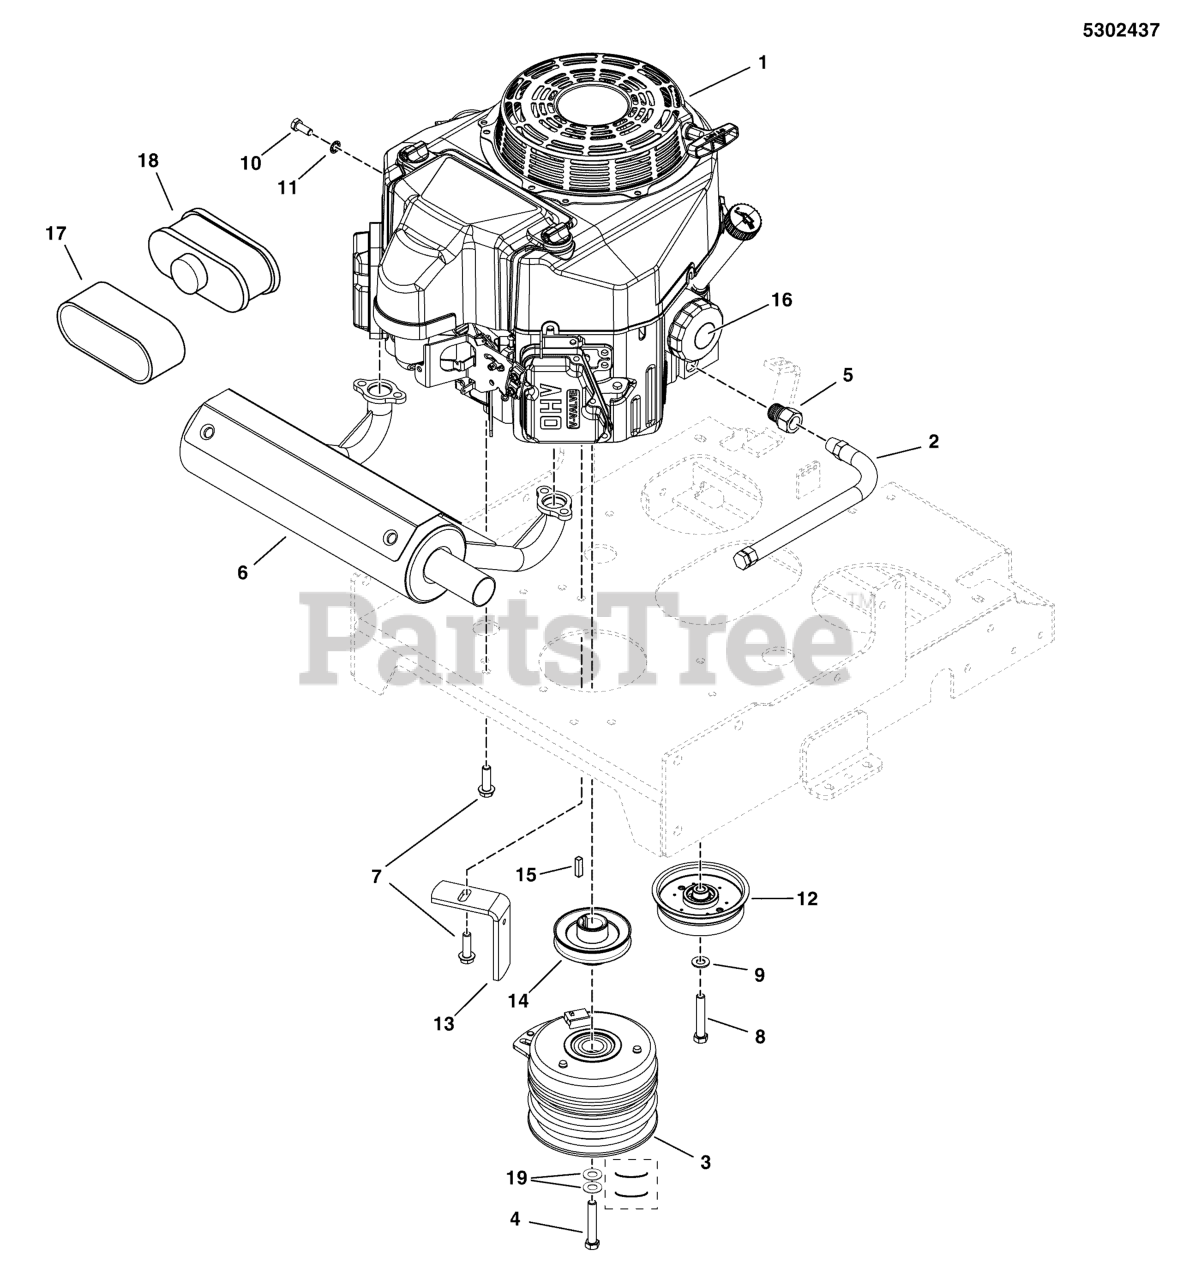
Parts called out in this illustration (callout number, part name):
1	ENGINE, KAWASAKI, MANUAL START, FS SERIES
2	HOSE, OIL DRAIN
3	CLUTCH, WARNER, 125 ft lbs - 1"
4	BOLT, CRANKSHAFT, 7/16-20 X 3, GD8
5	ADAPTER-OIL DRAIN
6	MUFFLER, KAWASAKI, HORIZONTAL
7	BOLT,HEX FLG,SER GD5 3/8-16X1-1/4PACH CZ
8	BOLT, 3/8-16 X 2 GD5 TFL
9	WASHER, 3/8 SAE
10	BOLT, M8-1.25 X 20MM GD8.8
11	WASHER, 5/16 INT. TOOTH LOCK
12	PULLEY, IDLER, SINGLE FLANGE, 4" OD
13	ANCHOR, CLUTCH, SINGLE HOLE - RED
14	PULLEY, CRANKSHAFT, 1.0005 ID X 4.25 OD
15	KEY, 1/4 SQ X 1
16	FILTER, OIL (SV)
17	FILTER, AIR, OUTER (SV)
18	FILTER, AIR, INNER (SV)
19	BELLEVILLE WASHER 1.1875 X .442 X .089
